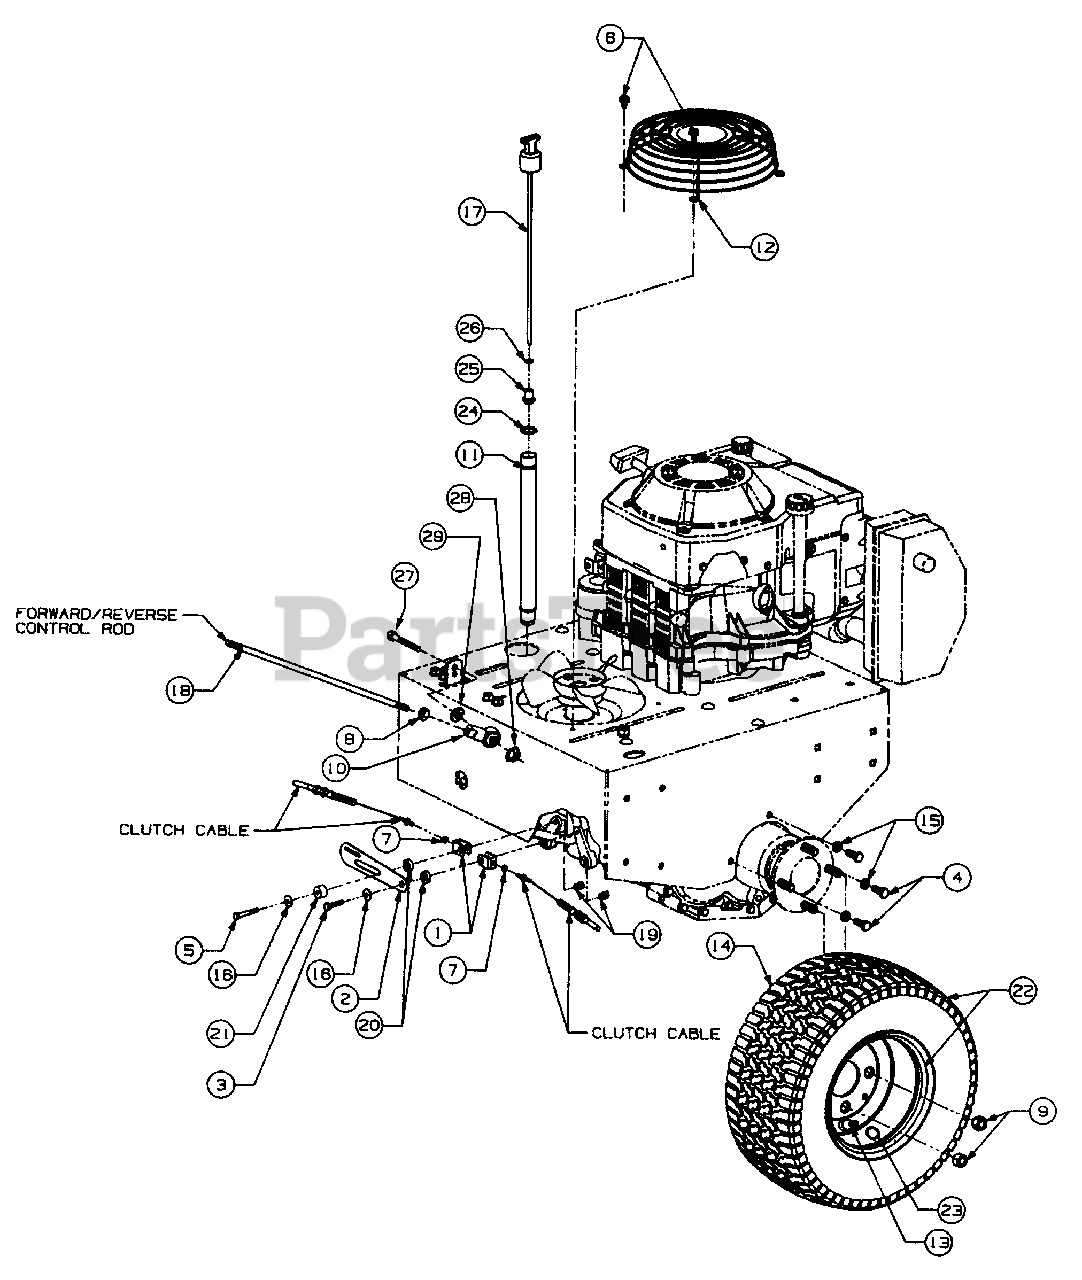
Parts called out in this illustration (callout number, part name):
1	U-Clevis, Clutch Cable
2	Plate, Parking Brake Switch Mount
3	Screw, Hex Cap 1/4-28 X 1.25 Lg GR 5)
4	Screw, Hex Cap 3/8-16 X 1.0 Lg GR 5
5	Screw, Hex Cap 1/4-28 X 1.75 Lg GR 5
6	Screw, Hex Wash. Hd. Tapp 5/16-18 X .50 Lg
7	Nut, Hex Jam, #10-32
8	Nut, Hex Jam, 3/8-24 GR 5
9	Nut, Lug, 1/2-20
10	Rod End, Spherical
11	Tube, Oil Fill
12	Guard, FAn Cover
13	Valve, Tubeless Air
14	Tire, Turf Chief, 16 X 6.5-8
15	Washer, Lock, 3/8
16	Washer, Bell, .265 X .75 X .062 Thk
18	Rod, F/R Control
19	Nut, Clevis Spacer, 1/4-28
20	Spacer, Clevis
21	Spacer, Switch Engagement
22	Wheel & Tire Assy, Complete, 16 X 6.50-8
23	Label, Inflation
25	Seal, Rubber
26	Washer, Plain, 5/16
27	Screw, Hex Cap, 3/8-16 X 1.25
28	Nut, Flanged Lock, 3/8-16
29	Washer, Flat, .407 X .812 X .135 HDN
